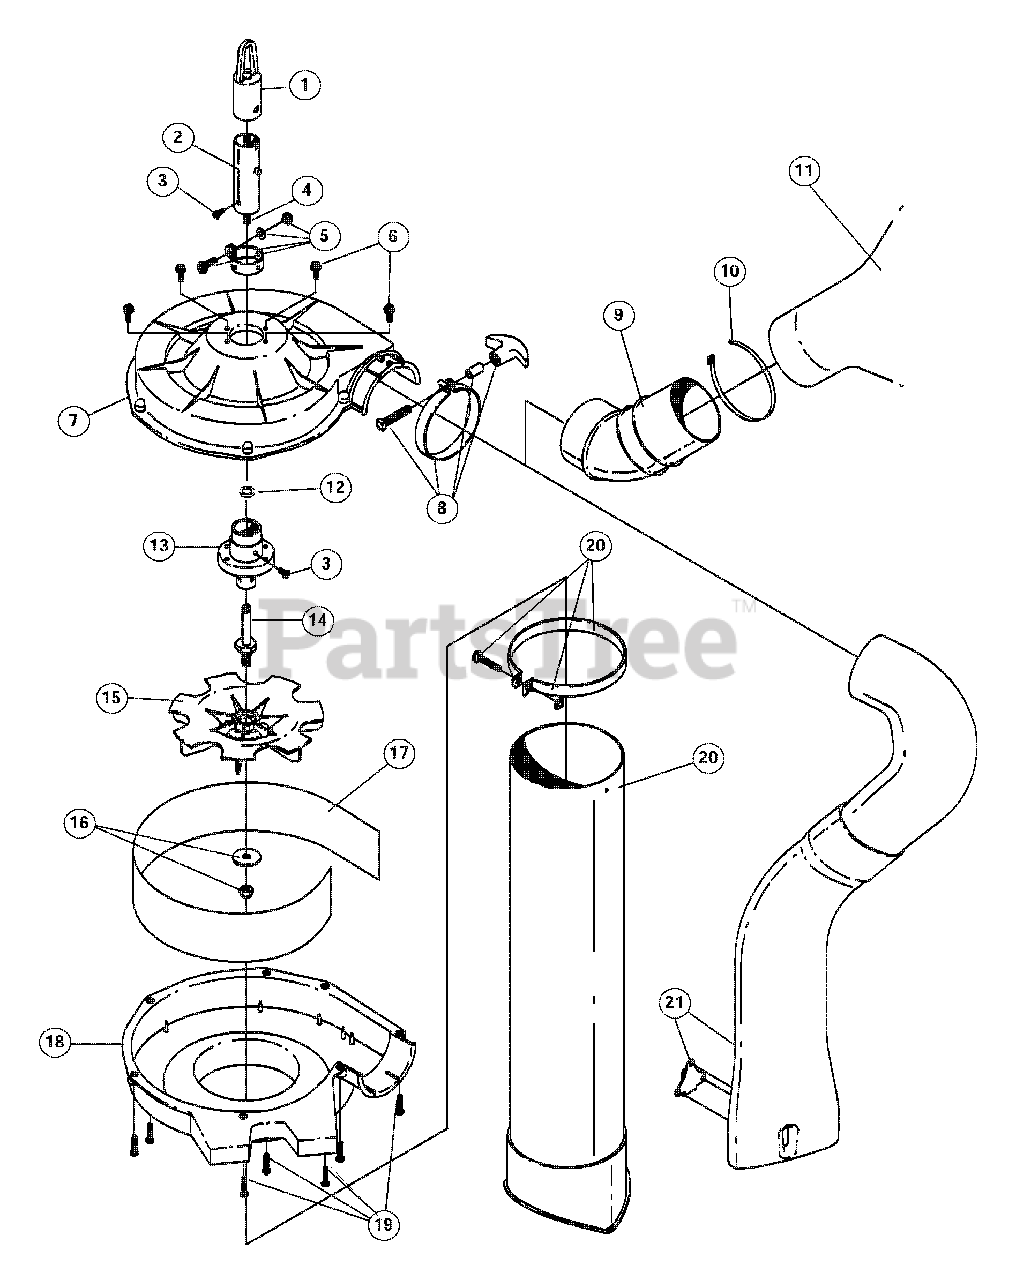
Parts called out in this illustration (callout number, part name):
1	Hanger
2	Boom Assembly
3	Anti-Rotation Screw
4	Drive Shaft Assembly
5	Lower Clamp Assembly
6	Mounting Screw
7	Upper Housing
8	Clamp Assembly
9	Adapter
11	Vacuum Bag Assembly
12	Palnut
13	Bushing Housing Assembly
14	Impeller Shaft
15	Impeller
16	Nut and Washer Assembly
18	Lower Housing
19	Mounting Screw
20	Vacuum Tube Assembly
21	Blower Tube Assembly
